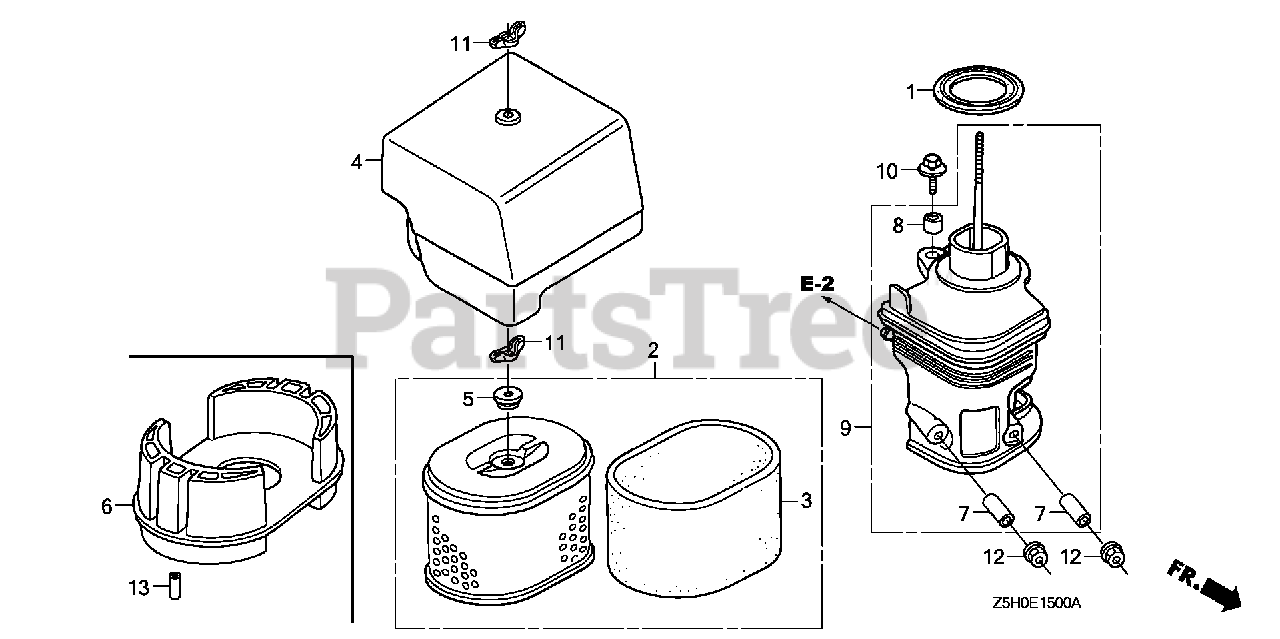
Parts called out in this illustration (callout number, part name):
1	GASKET, ELBOW
2	ELEMENT, AIR CLEANER (DUAL)
3	FILTER (OUTER)
4	COVER, AIR CLEANER
5	GROMMET, AIR CLEANER
6	NOSE, MUFFLER
7	COLLAR, AIR CLEANER
8	COLLAR B, AIR CLEANER
9	ELBOW, AIR CLEANER
9	ELBOW COMP, AIR/C
10	BOLT-WASHER (6X22)
11	NUT, TOOL BOX SETTING
12	NUT, FLANGE (6MM)
